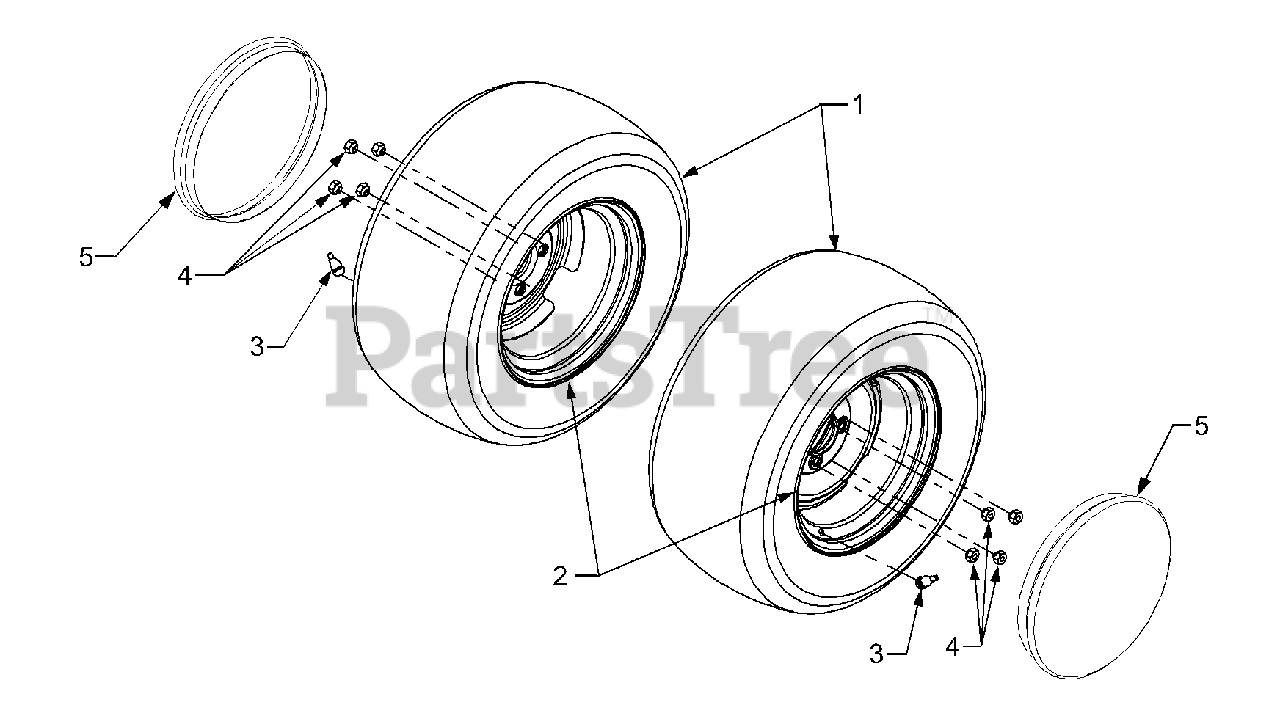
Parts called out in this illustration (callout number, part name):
1	Tire, Turf, 24 x 10.5 - 12
2	Rim Assembly, Wheel
3	Valve, Tubeless Air
4	Lug Nut, 7/16-14
5	Hubcap, Rear
